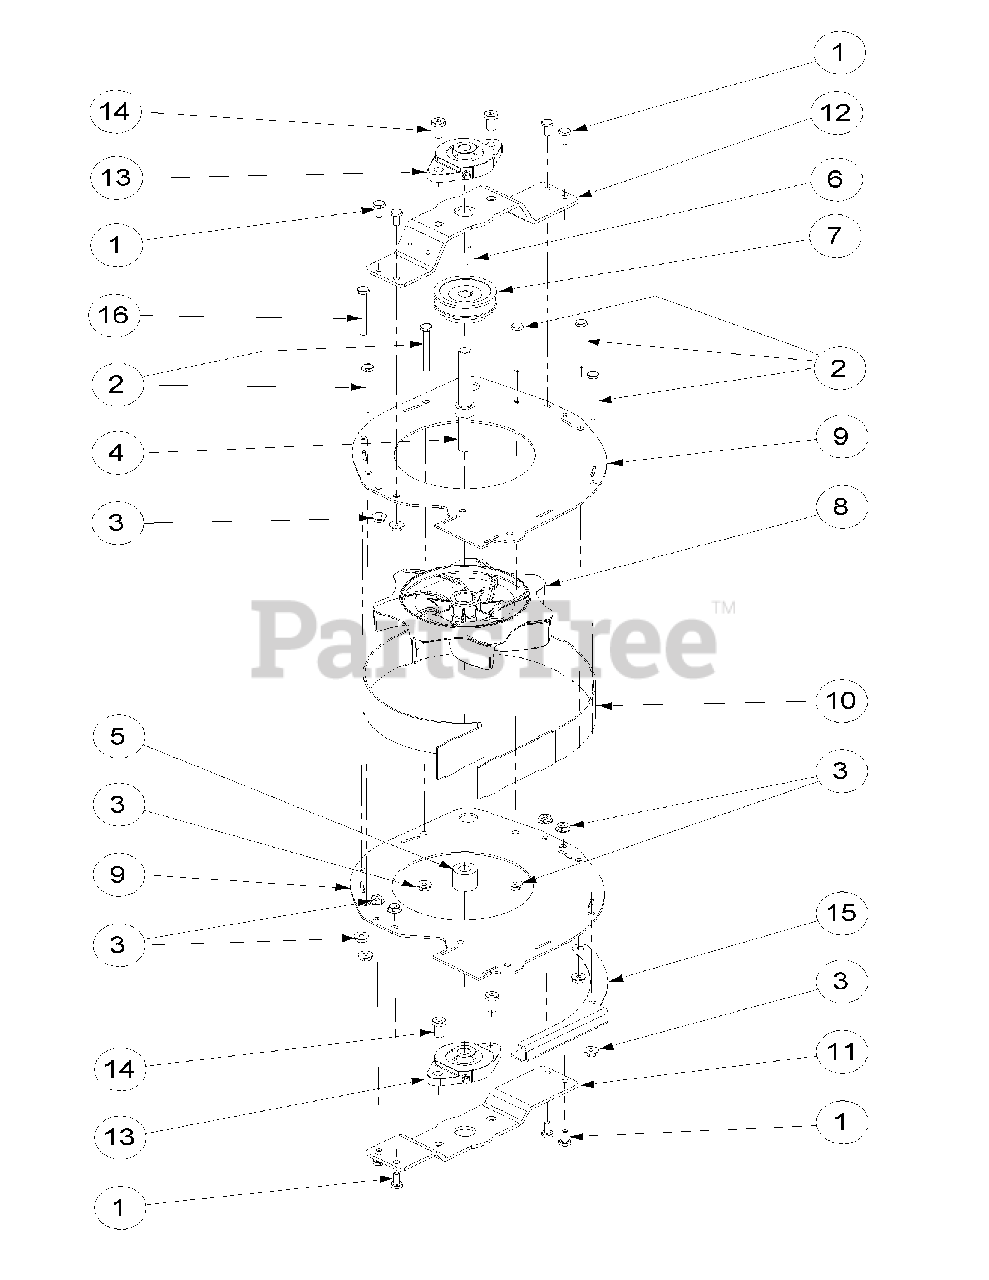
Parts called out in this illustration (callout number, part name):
1	HHCS, 1/4-20 x 0.620
2	HHCS, 1/4-20 x 2.50
3	Hex Nut Flange Lock, 1/4-20
4	Blower Shaft
5	Blower Spacer
6	Key, 1/8 x 1/8 x 1.00
7	Cast Pulley, .500 ID x 2.50 OD
8	Blower Impeller
9	Blower Housing Cover
10	Blower Housing Band
11	Bottom Bearing Mounting Plate
12	Top Bearing Mounting Plate
13	Flange Bearing
14	Socket Head Screw, 3/8-16 x .75
15	Guard Deflector
16	HHCS, 1/4-20 x 2.75
